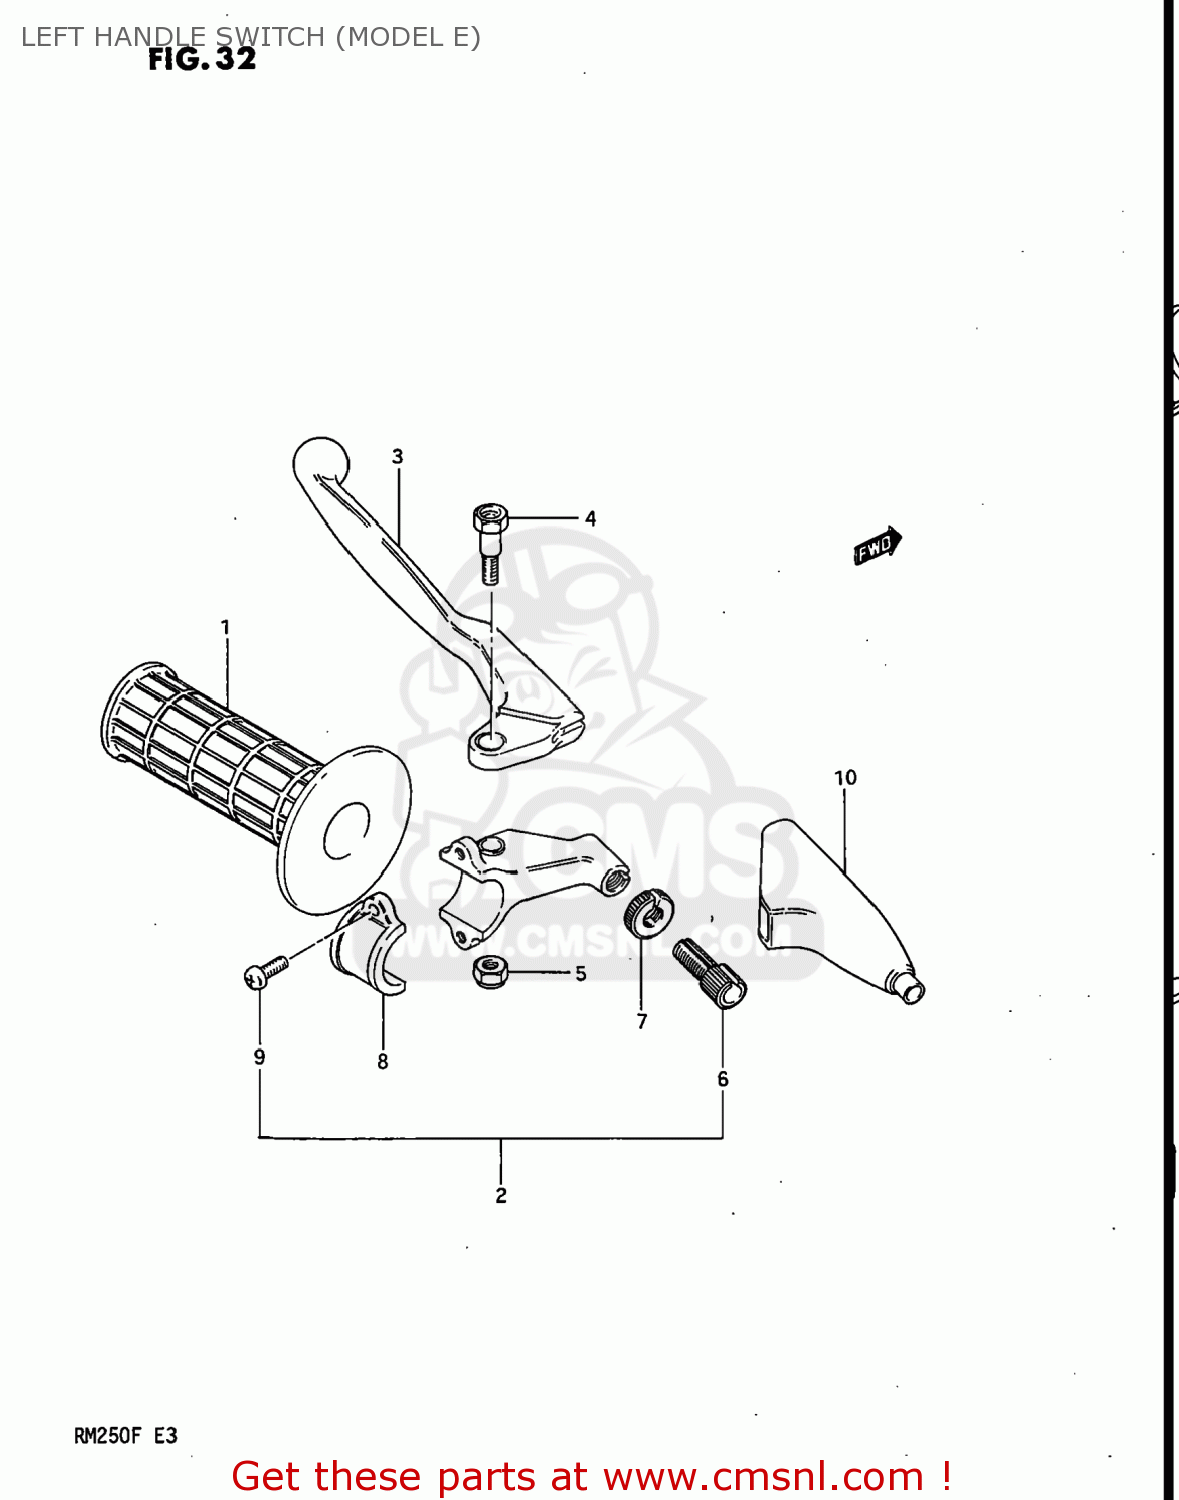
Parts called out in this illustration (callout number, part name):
1	GRIP,LEFT
2	LEVER ASSY,CLUTCH
3	LEVER,CLUTCH
4	BOLT,LEVER
5	NUT 6MM
6	ADJUSTER,CABLE
7	NUT,CABLE ADJUSTER
8	BRACKET,CLUTCH LEVER HOLDER
9	SCREW
10	COVER,CLUTCH LEVER
